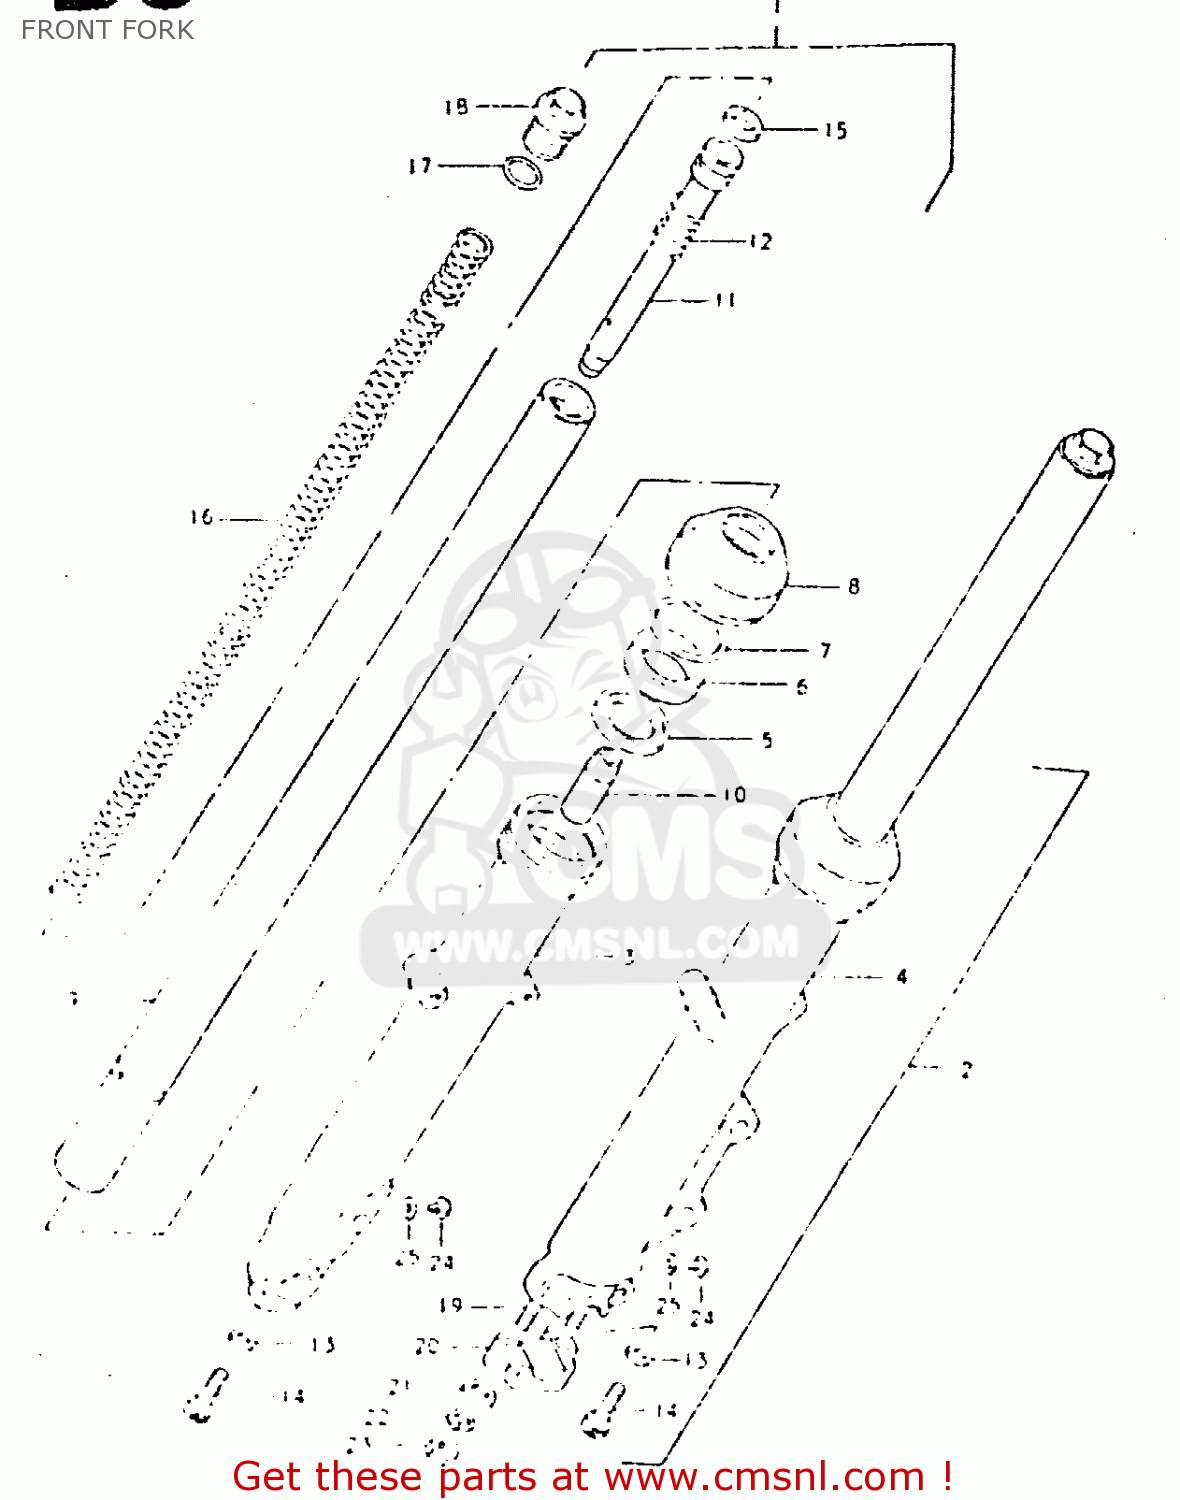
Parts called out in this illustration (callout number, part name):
1	DAMPER ASSEMBLY,RIGHT
2	DAMPER ASSEMBLY,LEFT
3	TUBE,FORK,OUTER,RIGHT
4	TUBE,FORK,LEFT,OUTER
5	SPACER,OIL SEAL
6	OIL SEAL,FRONT FORK
7	CIRCLIP,FORK OIL SEAL
8	BOOT
9	TUBE,FORK,INNER
10	PIECE,OIL LOCK
11	CYLINDER,FRONT FORK
12	SPRING,REBOUND
13	GASKET (NAS)
14	BOLT(8X27)
15	RING,PISTON
16	SPRING
17	O RING
18	BOLT
19	STUD 8X25
20	HOLDER,AXLE
21	WASHER
22	LOCK WASHER
23	NUT (8MM)
24	SCREW 4X6
25	GASKET (NAS)
